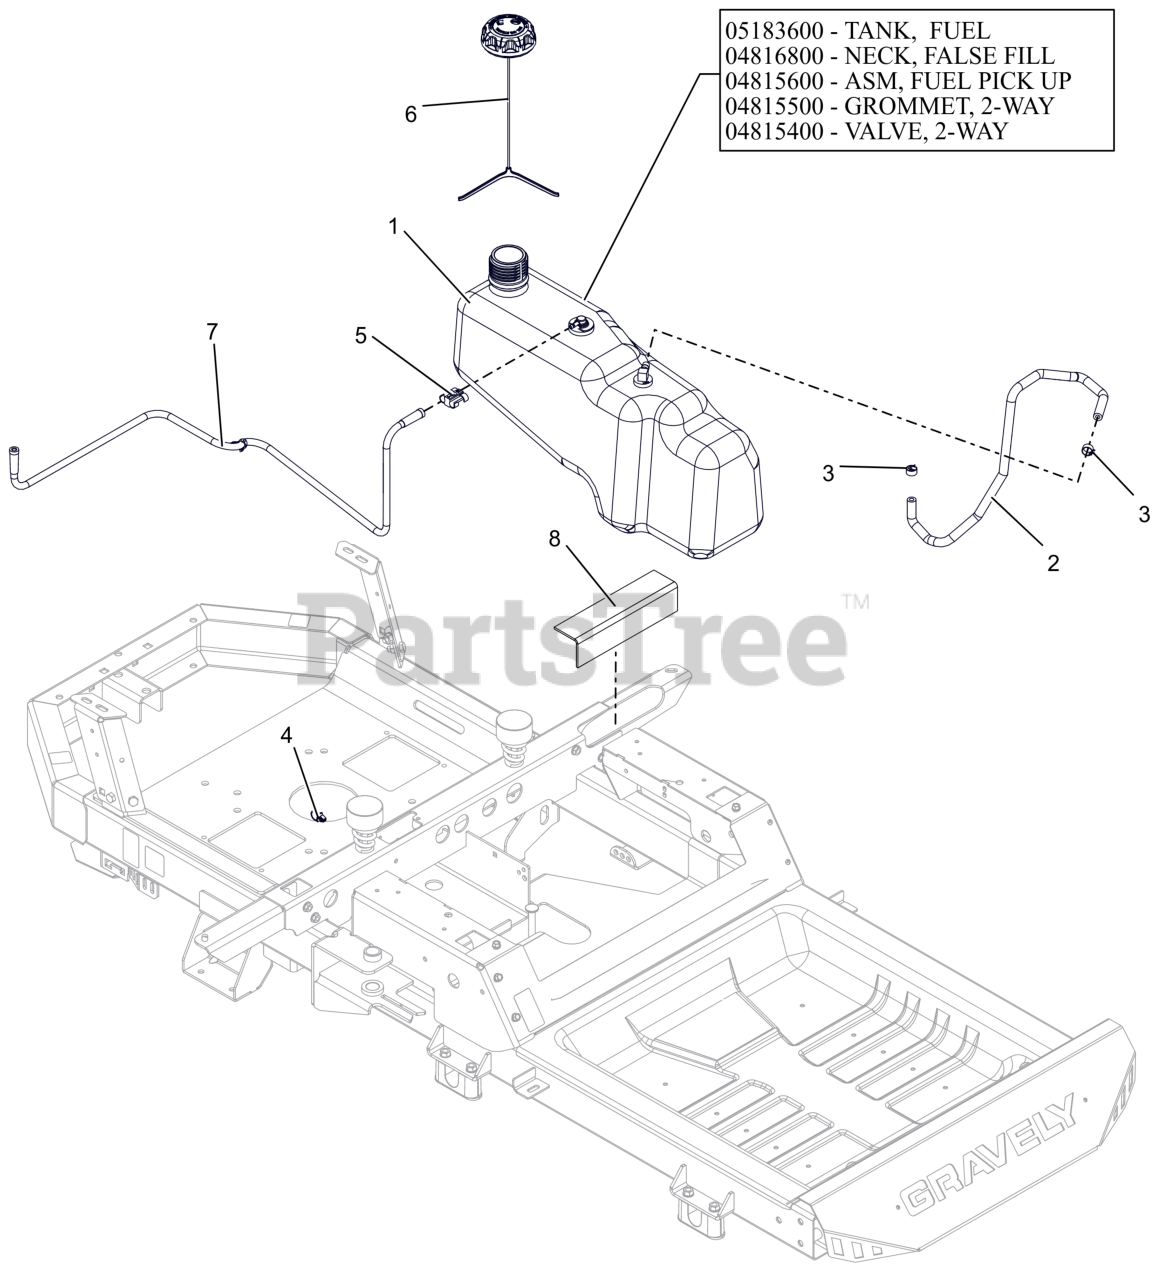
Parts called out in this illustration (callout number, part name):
1	ASM, FUEL TANK - ZTX
1	TANK, FUEL-ZTX
1	NECK, FALSE FILL ZOOM/ZT
1	ASM, FUEL PICK-UP ZOOM/ZT 2015
1	GROMMET, 2-WAY
1	VALVE, 2-WAY
2	HOSE, .25 LOW-PERM BULK GAS
3	CLAMP, FUEL LINE
4	ROUTING CLIP (1/2" ID)
5	CLIP, T, .38-.50
6	CAP, FUEL VENT-IN 2.25" RATCH.
7	LINE, FUEL VENT KOHLER SMCHOKE
8	PAD, RUBBER-TANK
